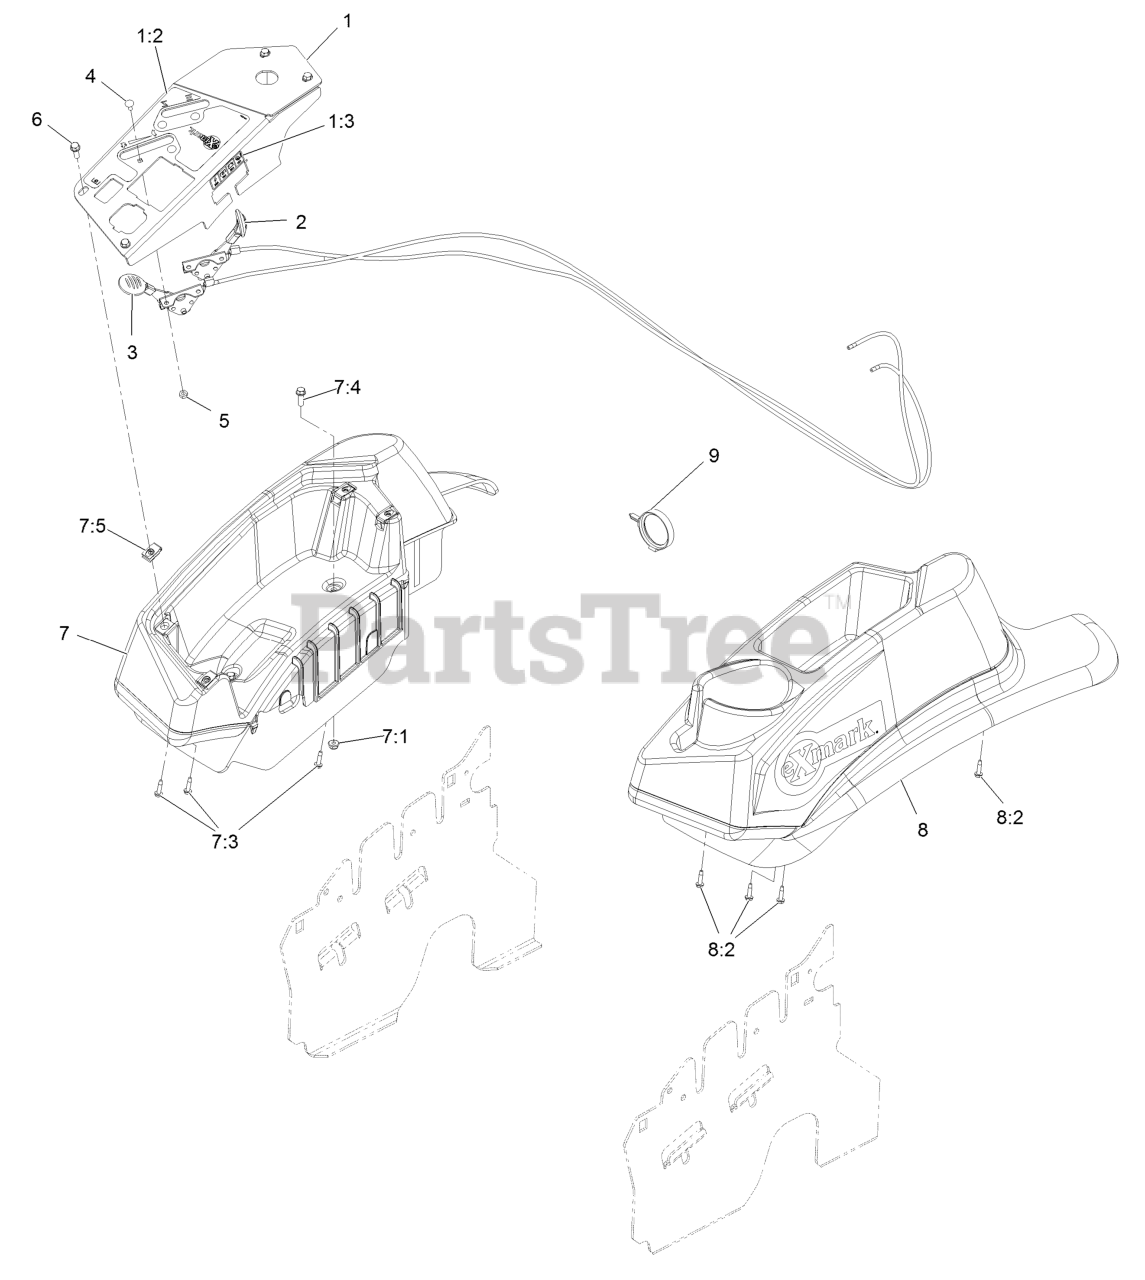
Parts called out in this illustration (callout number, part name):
1	CONSOLE,PANEL W/DECAL
1:2	DECAL-CONTROL PANEL NON-E
1:3	DECAL-FUSES
2	ASM, CHOKE CABLE
3	ASM,THROTTLE CABLE
4	BOLT-CARR
5	NUT-LOCK, NI
6	SCREW-HWH
7	CONSOLE,RH NARROW ASM
7:3	SCREW,THD FORM,HWH
7:4	SCREW-HWH
7:5	Nut-Retainer-Panel 1/4-20
8	CONSOLE.LH NARROW ASM
8:2	SCREW,THD FORM,HWH
9	CLAMP-HARNESS
